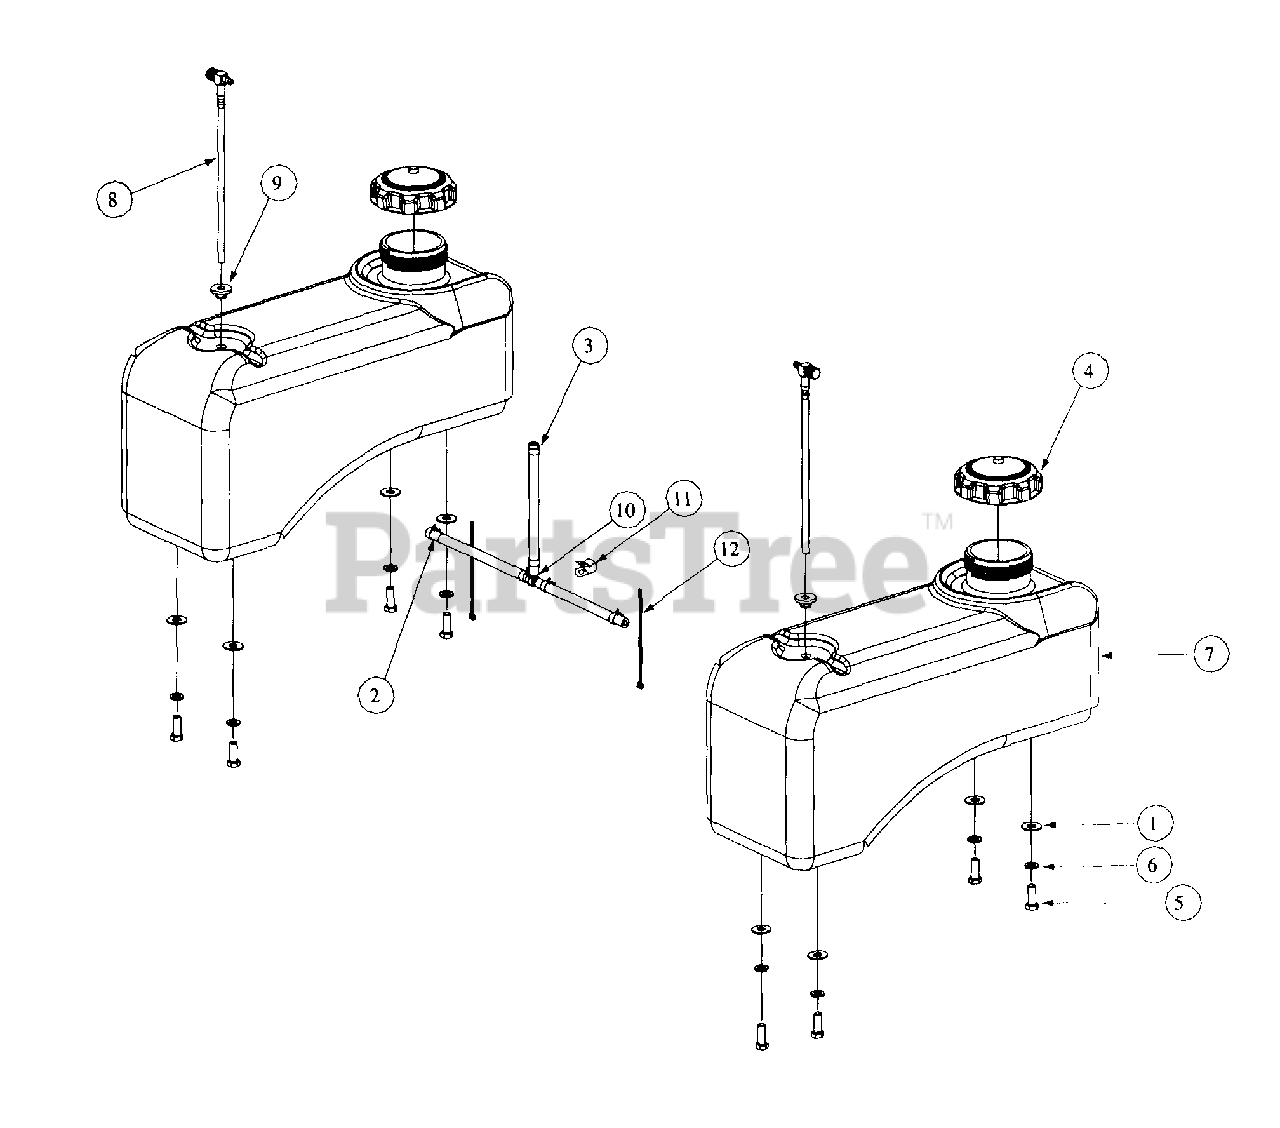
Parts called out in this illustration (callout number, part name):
1	Flat Washer, .406 ID, 1.0 OD, .105
2	Hose, 1/4" Fuel Line
3	Clamp, Union
4	Fuel Cap, 3.5
5	Hex, Cap Screw, 3/8-16, .88
6	Lock Washer, 3/8
7	Fuel Tank
8	Fuel Fitting
9	Bushing, Fuel Tank
10	Tee Fitting, Fuel
12	Cable Tie
